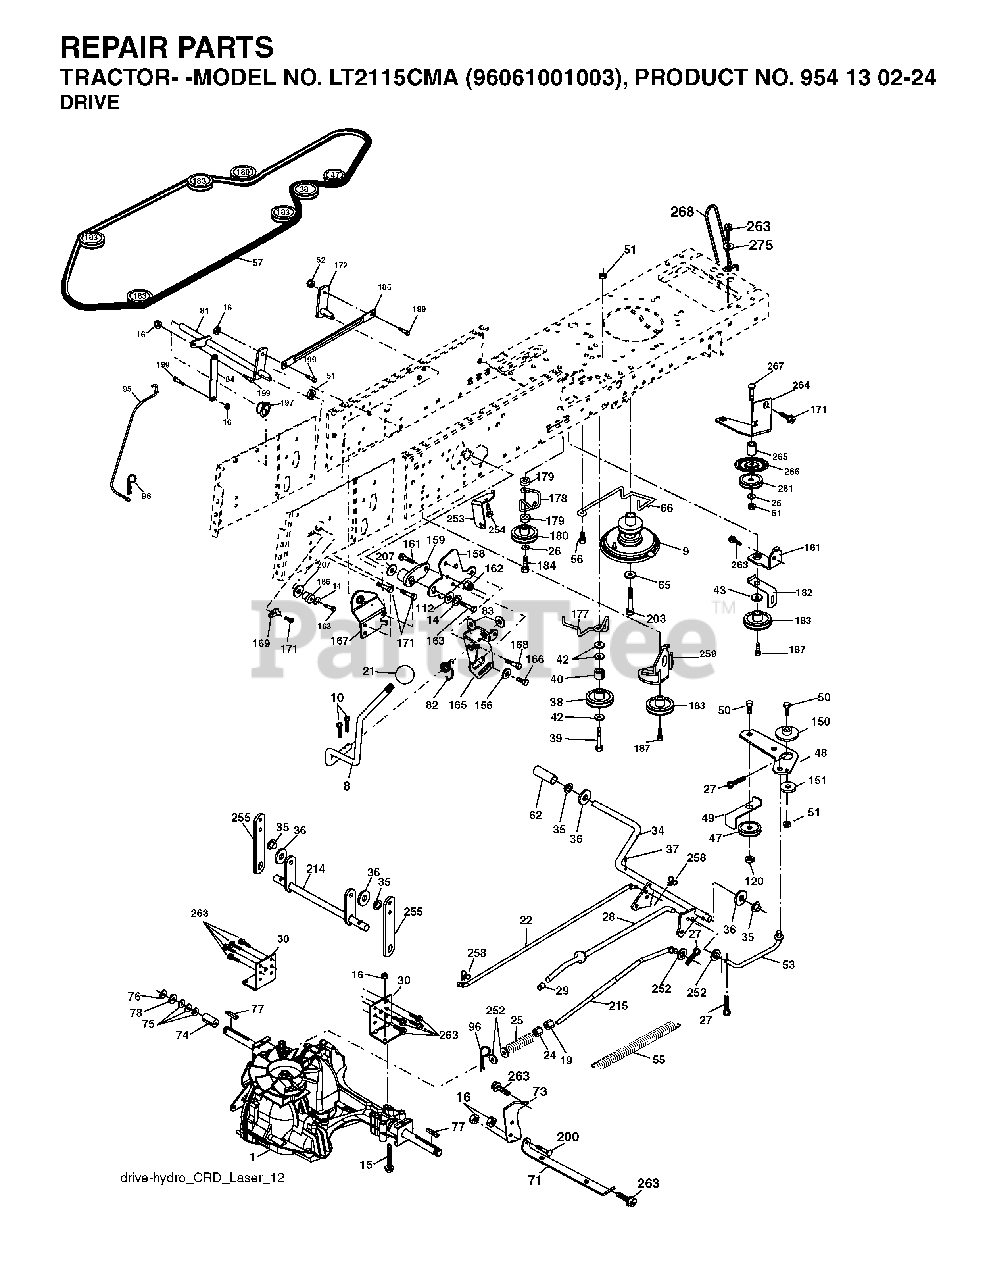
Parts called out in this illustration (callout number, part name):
8	ROD SHIFT
10	PIN COTTER
14	LOCKWASHER
16	NUT.71038.31-18.HEX.NYLOCK
19	NUT
21	KNOB.DELUXE.(PISTOL.GRIP).BLAC
24	NUT
27	COTTER PIN
28	ROD, PARKING BRAKE
29	PLUNGER CAP
30	BRKT, TRNSXLE MNT 20"
34	SHAFT, FOOT PEDAL
35	BEARING.NYLON
36	WASHER LT
37	DRIVE PIN
38	PULLEY.FLAT
42	WASHER
47	IDLER PULLEY
48	BELLCRANK, CLUTCH
49	RETAIN BELT
50	BOLT.3/8-16X1.50
51	LOCKNUT
52	LOCKNUT
53	LINK, CLUTCH LT
55	SPRING, RETURN LT
56	SCREW.3/8-16
62	PEDAL COVER T
65	LOCKWASHER
66	KEEPER BELT ENGINE
71	STRAP TORQUE RH HYDRO
73	STRAP TORQUE LH HYDRO
74	SPACER AXLE
76	E-RING LT
77	SQUARE KEY
81	SHAFT ASSY
82	SHIFT SPRING
83	WASHER
96	RETAINER M
112	WASHER LT
120	NUT LOCK FLG 3/8-16 UNC
145	BOLT HEX 5/16-18 GR 5
150	BUSHING.BELLCRANK.GRD.DR
151	WASHER 12/32X2X10GA
156	WASHER.SRRTD.5/16
158	BRACKET
159	HUB.SHIFT
161	BOLT
162	NUT.CROWNLOCK.1/4
165	RP BRACKET
167	BRACKET
168	BOLT.SHOULDER.5/16-18X
169	PLATE.FASTENING.CROSS.SHAFT
180	PULLEY.FLAT.IDLER
184	SCREW.HXWSH.3/8
187	BOLT.5/16-18X1.25
197	NYLINER SNAP 5/8" ID
199	BOLT SHOULDER 5/16-18 UNC
200	BOLT
207	WASHER NYL
254	SCREW 3/8-16X1
258	CLIP RETAINER
261	FLAT IDLER PULLEY
263	SCREW, 3/8-16X3/4
265	SPACER IDLER
275	WASHER
